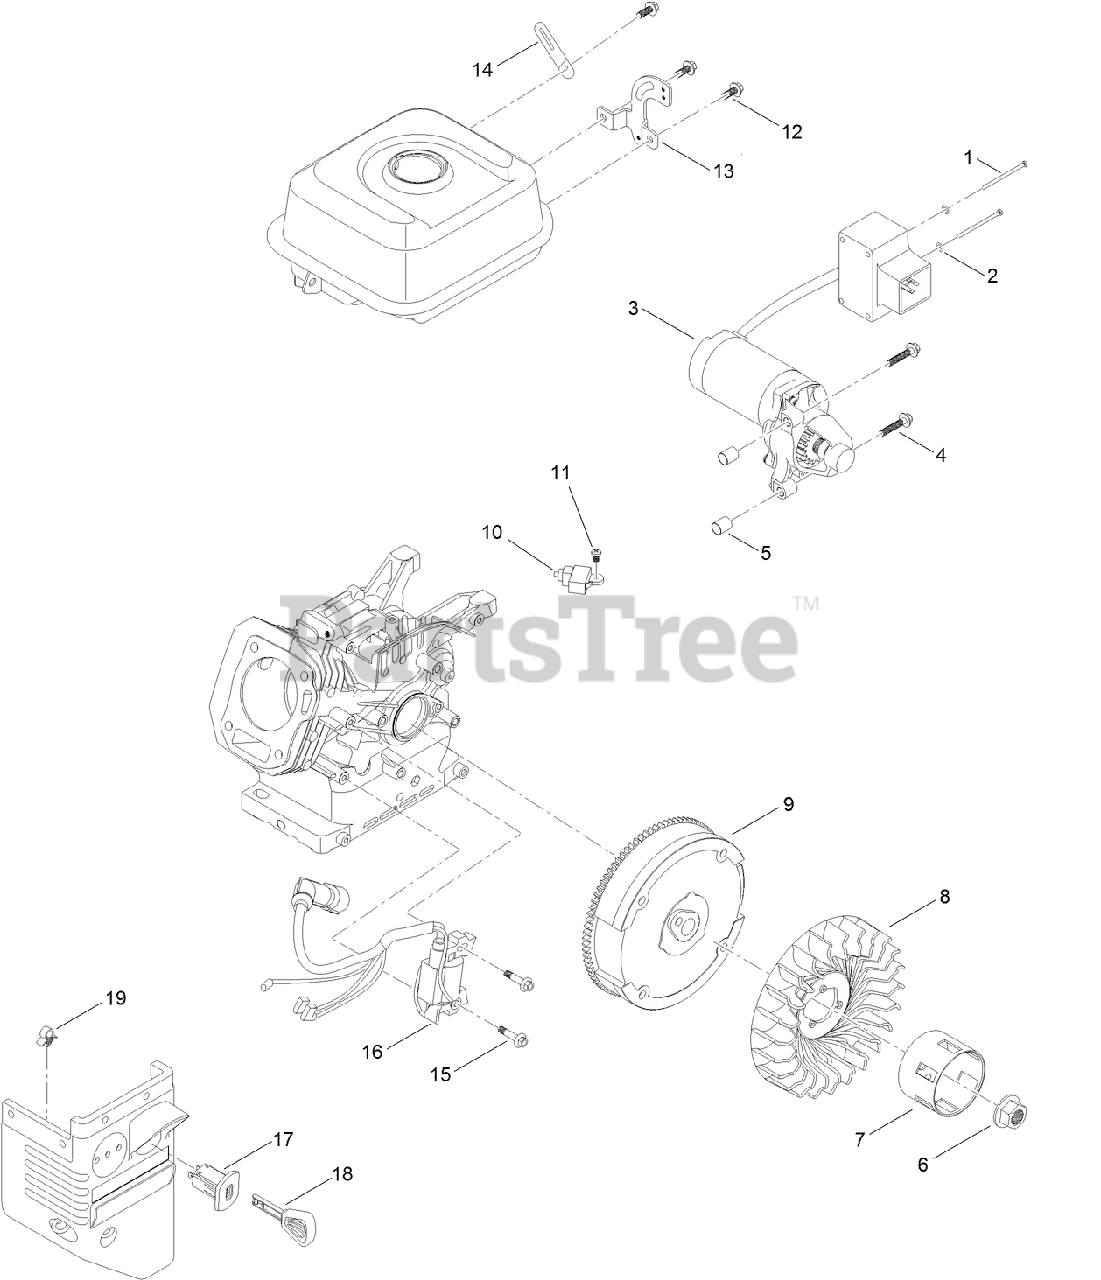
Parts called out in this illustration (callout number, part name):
1	SCREW-BHP
2	WASHER-PLAIN
4	SCREW-HHF
5	PIN-DOWEL
6	NUT-FLANGE
7	CUP-STARTER
9	FLYWHEEL
10	SWITCH-KILL, ENGINE
11	SCREW-PPH
12	SCREW-HHF
13	BRACKET
14	CLIP-HARNESS, WIRE
15	SCREW-HHF
17	SWITCH-KEY
